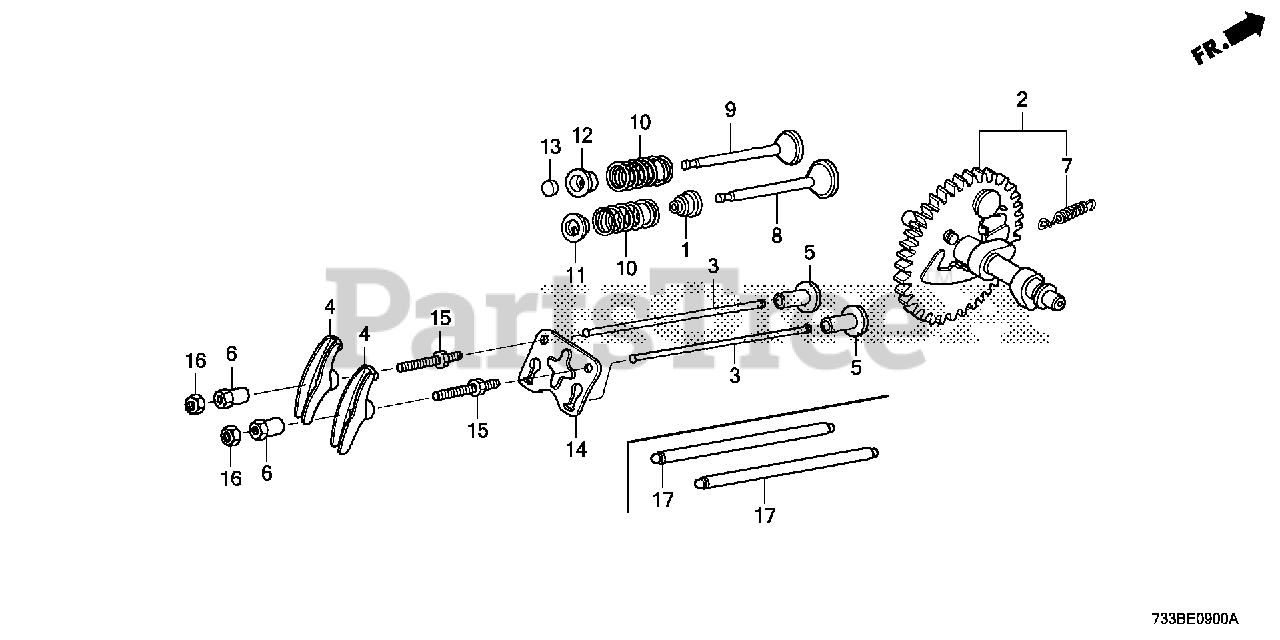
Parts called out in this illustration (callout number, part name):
1	SEAL, VALVE STEM
2	CAMSHAFT ASSY.
4	ARM, VALVE ROCKER
5	LIFTER, VALVE
6	PIVOT, ROCKER ARM
7	SPRING, WEIGHT RETURN
8	VALVE, IN.
9	VALVE, EX.
10	SPRING, VALVE
11	RETAINER, IN. VALVE SPRING
11	RETAINER, VALVE SPRING
12	RETAINER, IN. VALVE SPRING (EXHAUST SIDE)
12	RETAINER, VALVE SPRING
14	PLATE, PUSH ROD GUIDE
15	BOLT, PIVOT (8MM)
16	NUT, PIVOT ADJUSTING
